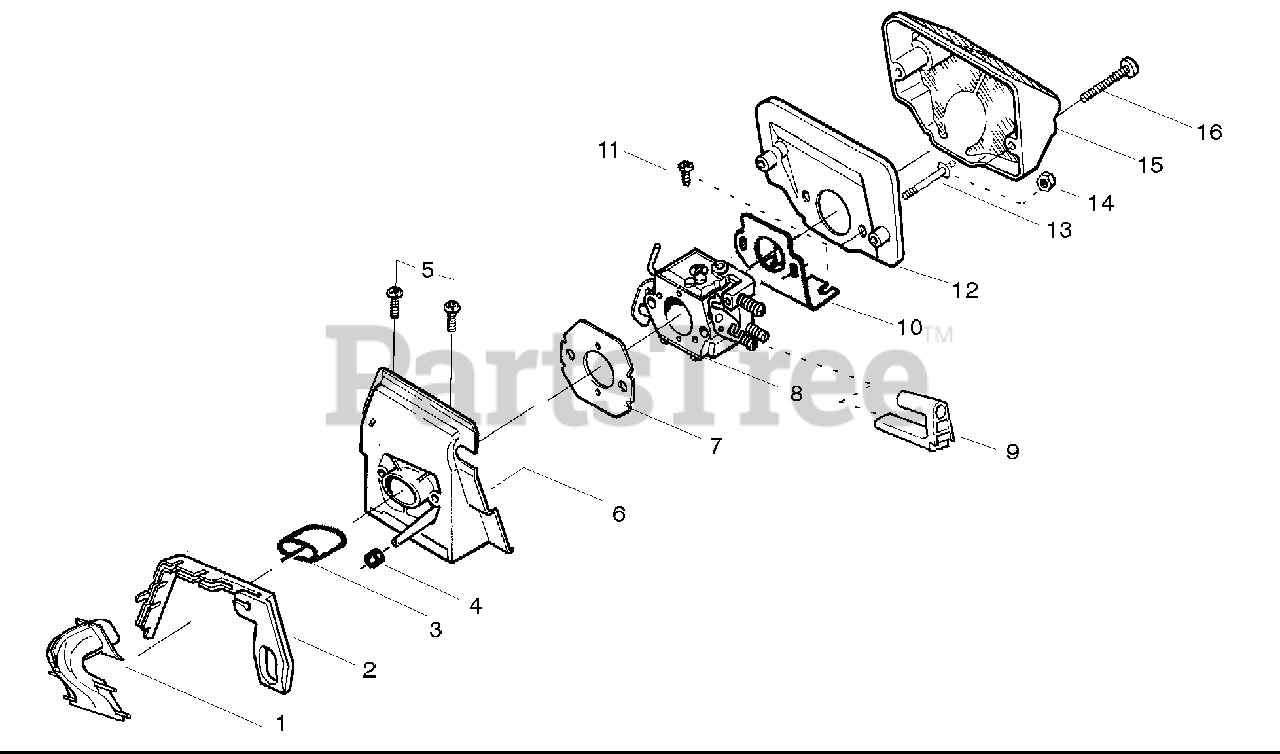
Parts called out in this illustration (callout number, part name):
1	Assy-Turbo Air Cleaner
2	Seal - Turbo Clean
3	Sleeve-Intake
4	Seal-Impulse
6	Adapter - Carb.
7	Gasket-Carburetor
8	Carburetor
8	WT-540
8	WT-660
9	Grommet-Final
10	Plate - Support
12	Air Filter - Bottom
13	Stud - Carb.
15	Air-Filter - Top
